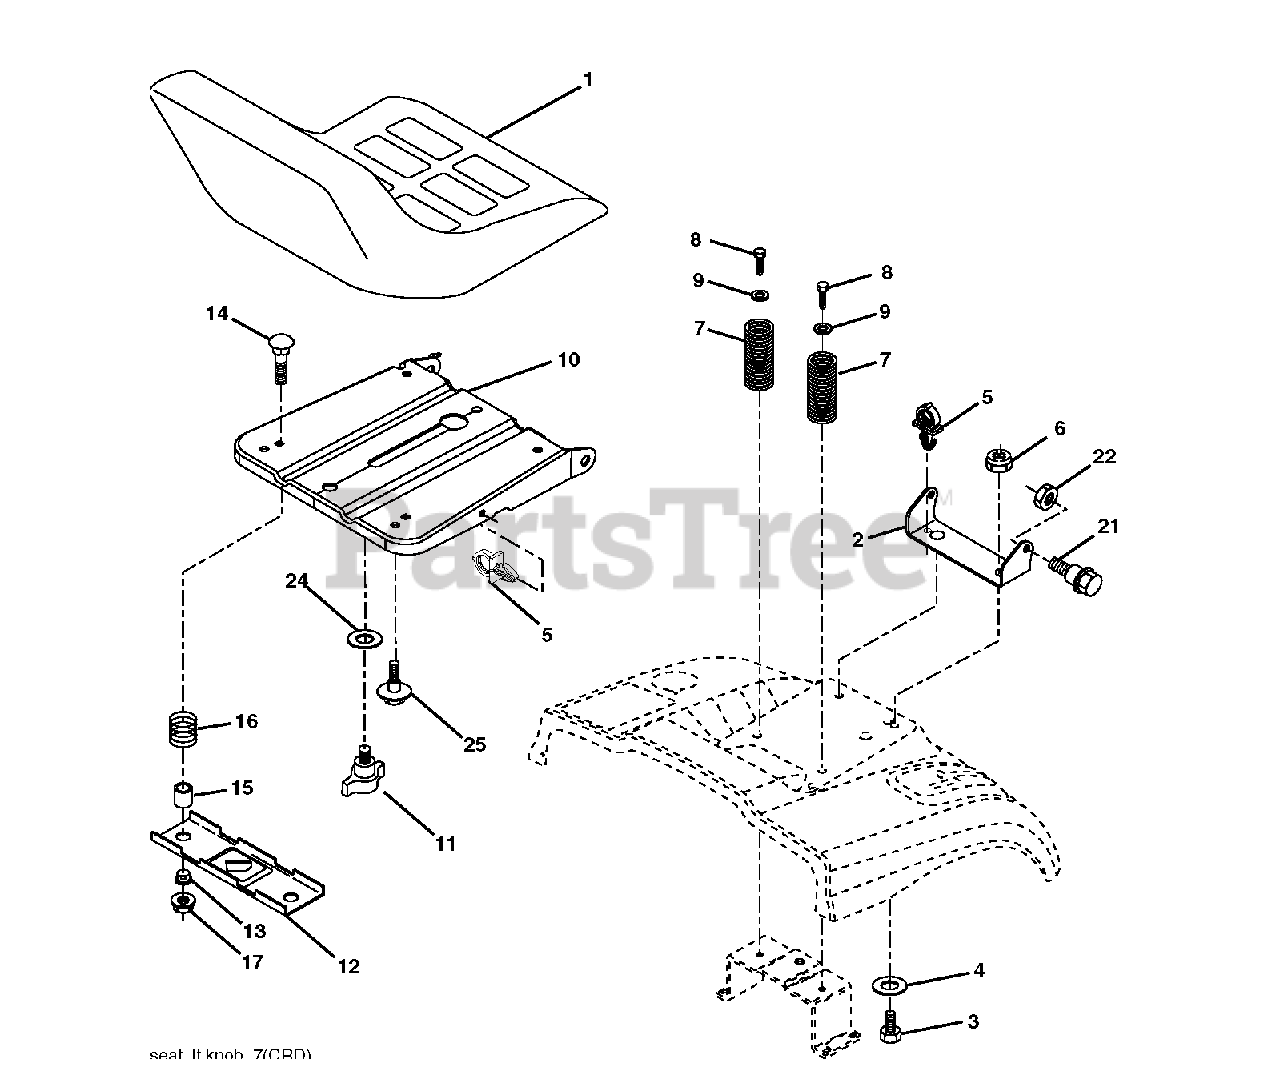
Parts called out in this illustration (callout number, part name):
1	SEAT.XG150.BLK.KB/SLD.NO-LOGO
2	SEAT PIVOT BRKT
3	BOLT, HEX 3/8-16X1
6	NUT
7	SPRING COMPRESSION
8	SCREW 3/8-16X1
9	WASHER
10	PAN.ASM.SEAT.1SLOT
11	KNOB.SEAT.ADJ.WINGNUT
12	BRKT.MNTNG.SWITCH.SEAT
14	BOLT.ROUND.HEAD.SQUARE.NECK
16	SPRING COMPRESSED
17	NUT T
21	BOLT.SHOULDER.5/16-18
22	NUT.71038.31-18.HEX.NYLOCK
